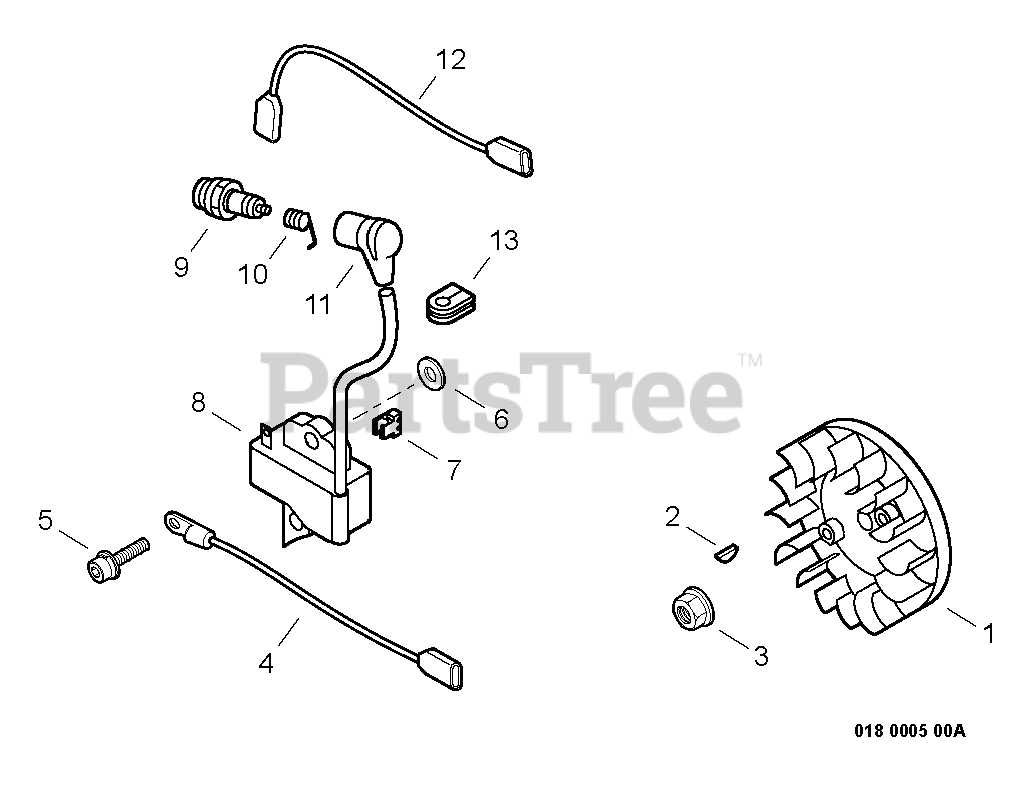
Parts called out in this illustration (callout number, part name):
1	FLYWHEEL
3	NUT - 8 -- FLANGE
4	LEAD - GROUND
5	SCREW - 5X20
8	COIL, IGNITION
9	SPARK PLUG -- BPM-8Y
10	TERMINAL, SPARK PLUG CAP
11	CAP, SPARK PLUG
12	LEAD - IGNITION
13	GROMMET
